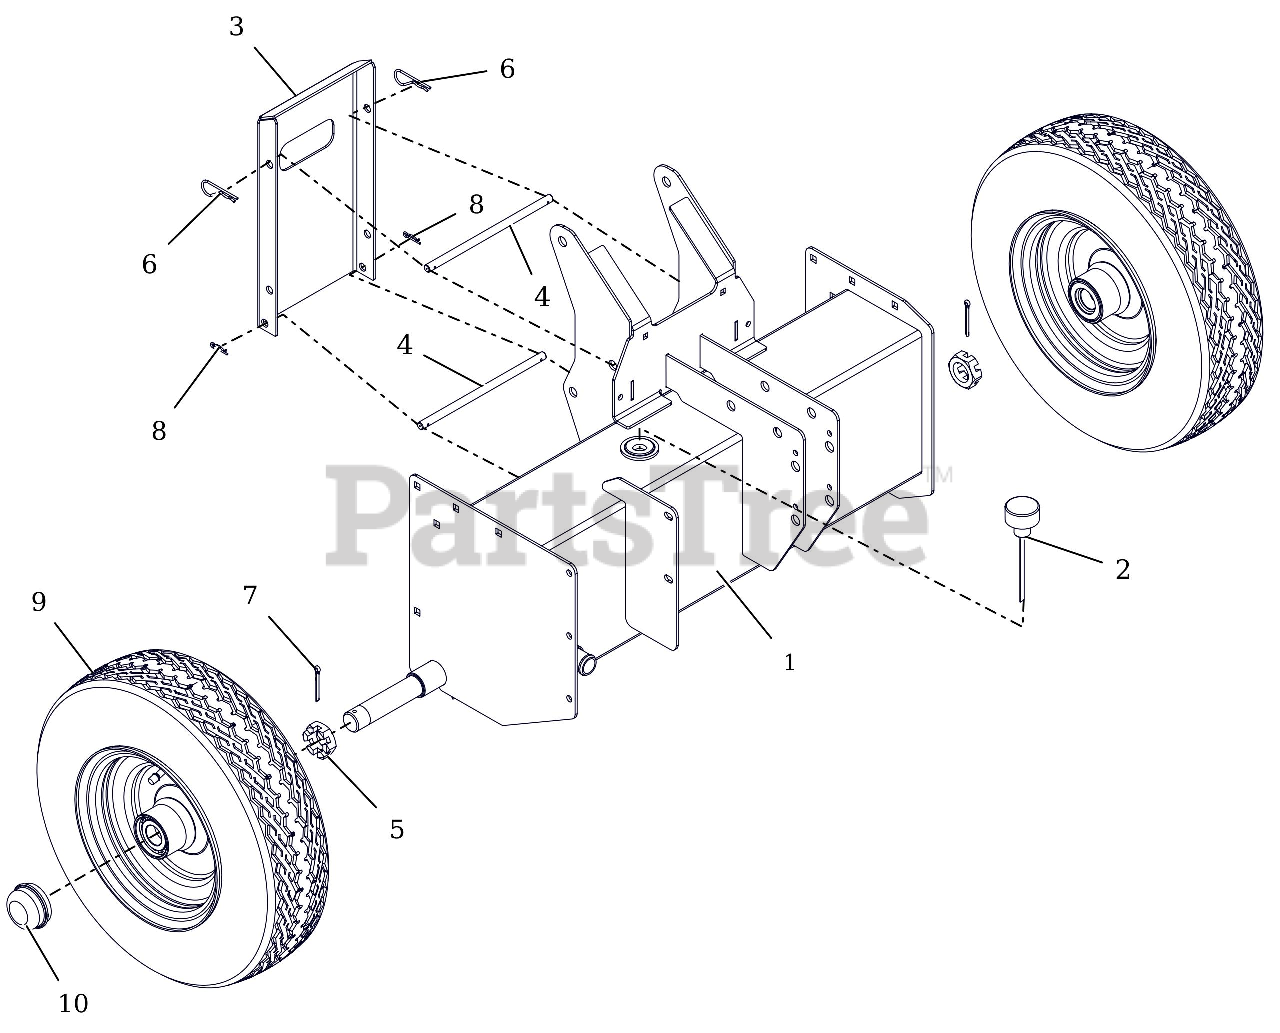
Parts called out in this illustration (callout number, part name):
1	CHASSIS-SPLIT W/SFTY DECAL-22T
2	BREATHER, DIPSTICK
3	REAR STAND W/DECALS (ARIENS)
4	PIN, .373 X 7.30 X 2X.109 THRU
5	NUT-SL 1.0-14
6	HAIRPIN, #7 CLIP .094X2.31 YWZ
7	@PIN-CTR .15X1.50 YWZC
8	PIN-HAIR, ENDRIES #25 YWZC
9	ASM,TIRE/WHEEL 4.8/4-8 P47GRAY
10	CAP-DUST
